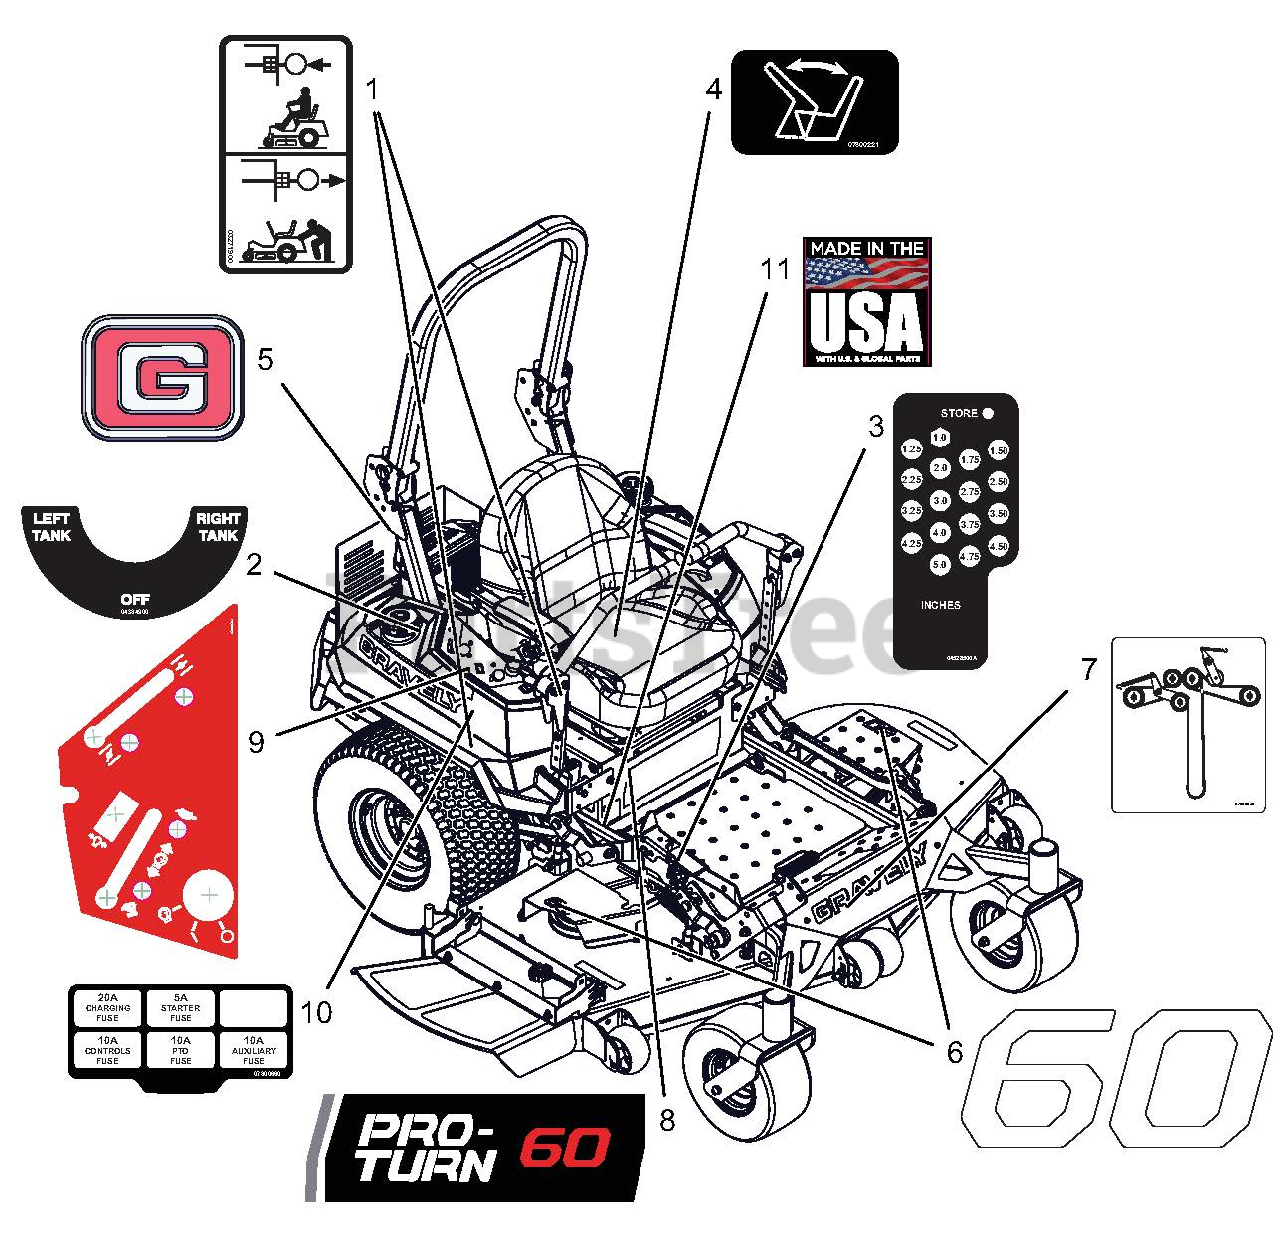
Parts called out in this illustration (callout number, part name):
1	DECAL, TRANSMISSION DISCONNECT
2	DECAL, FUEL VALVE
3	DECAL, HEIGHT OF CUT
4	DECAL - SEAT RELEASE
5	DECAL, GRAVELY BRAND
6	DECAL, 60"
7	DCL,BELT ROUTE-RH BK-SIDE IDLR
8	DECAL, PRO-TURN 60
9	DECAL, NON-EFI CONTROL PANEL
10	DECAL, FUSE BLOCK
11	DECAL, MADE IN USA
